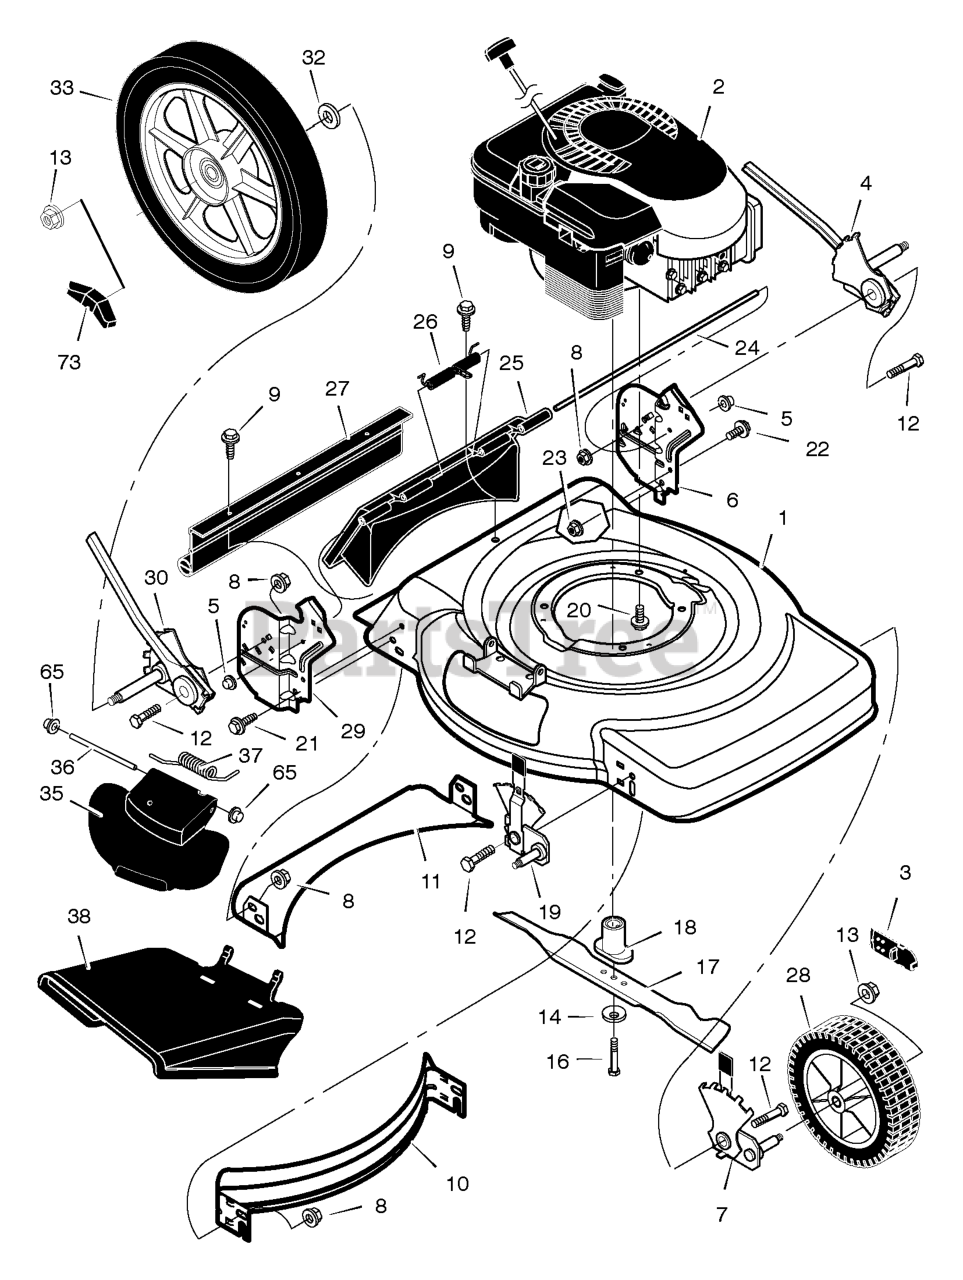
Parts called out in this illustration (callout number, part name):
2	Engine
3	Cap, Hub
4	Adjuster, Left Rear Height
5	Push Retainer
6	Bracket, Left Handle
7	Adjuster, Left Front Height
8	Nut, Flange
10	Baffle, Front
11	Baffle, Rear
13	Nut, Flange
14	Washer, Belleville
17	Blade
18	Adapter, Blade
19	Adjuster, Right Front Height
20	Bolt, Engine
21	Bolt
22	Bolt
23	Nut, Flange
24	Rod, Pivot
25	Door, Rear (Black)
26	Spring
27	Guard, Rear
28	Wheel & Tire, Front
29	Bracket, Right Handle
30	Adjuster, Right Rear Height
33	Wheel & Tire, Rear
35	Cover, Mulch (Black)
36	Rod, Pivot
37	Spring, Torsion
38	Deflector, Chute (Black)
65	Push On Cap
73	Knob
